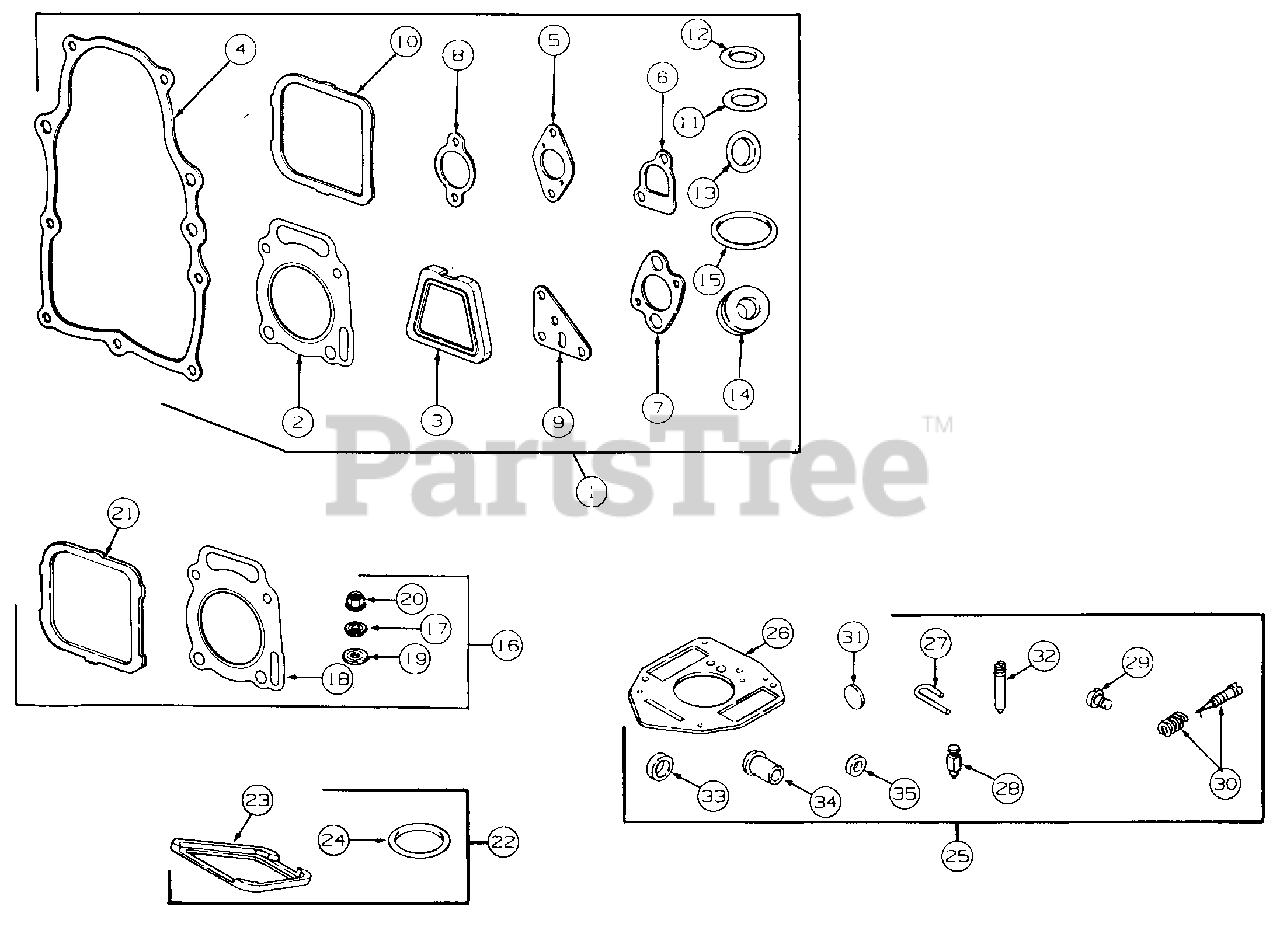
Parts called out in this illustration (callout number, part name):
1	Gasket Set
2	Gasket, Cylinder Head
3	Gasket, Breather
4	Gasket, Cover
5	Gasket, Carburetor Mtg
6	Gasket, Intake Manifold
7	Gasket, Air Cleaner
8	Gasket, Exhaust Manifold
9	Gasket, Adapter
10	Gasket, Valve Cover
11	O-Ring, Oil Pump
12	O-Ring, Crankcase Cover
13	O-Ring, Pick-Up Tube
14	Washer, Valve Cover
15	Seal, Breather Screw
16	Overhaul Kit, Valve
18	Gasket, Cylinder Head
19	Washer
20	Nut, Nylock
21	Gasket, Valve Cover
22	Gasket Set, Breather
23	Gasket, Breather
24	Seal, Breather Screw
25	Overhaul Kit, Carburetor
26	Gasket, Intake Elbow
27	Pin, Float Hinge
28	Valve, Fuel Inlet
29	Jet, Main
30	Valve, Idle Adjusting Needle
31	Plug, Welch
32	Jet, Slow Speed
33	Collar, Throttle
34	Collar, Choke
35	Seal, Shaft
